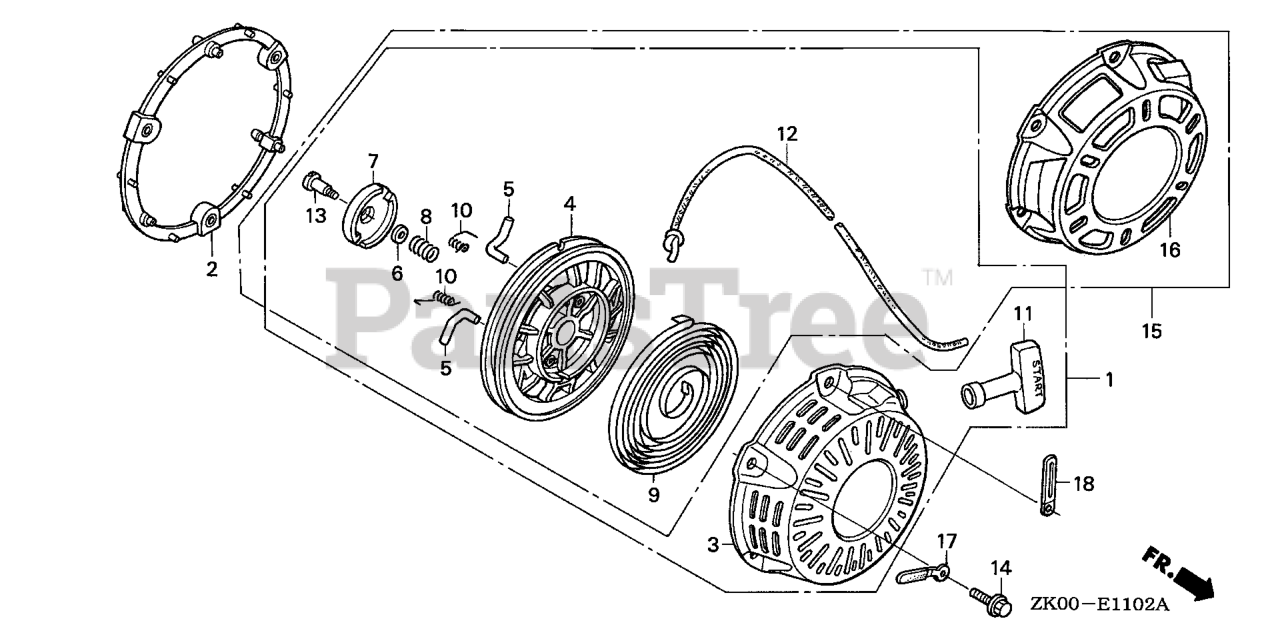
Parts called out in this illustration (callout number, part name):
1	STARTER ASSY., RECOIL *NH1* (BLACK)
1	STARTER ASSY., RECOIL *R280* (POWER RED)
2	SPACER, RECOIL STARTER MOUNTING *NH1* (BLACK)
2	SPACER, RECOIL STARTER MOUNTING *R280* (POWER RED)
3	CASE, RECOIL STARTER *R280* (Honda Code 7346836). (POWER RED)
3	CASE, RECOIL STARTER *NH1* (Honda Code 4193058). (BLACK)
4	REEL, RECOIL STARTER
5	RATCHET, STARTER
6	PLATE, FRICTION
7	GUIDE, RATCHET
8	SPRING, FRICTION
9	SPRING, RECOIL STARTER
10	SPRING, RETURN
11	GRIP, STARTER
12	ROPE, RECOIL STARTER (#5X55")
13	SCREW, SETTING
14	BOLT, FLANGE (6X18)
